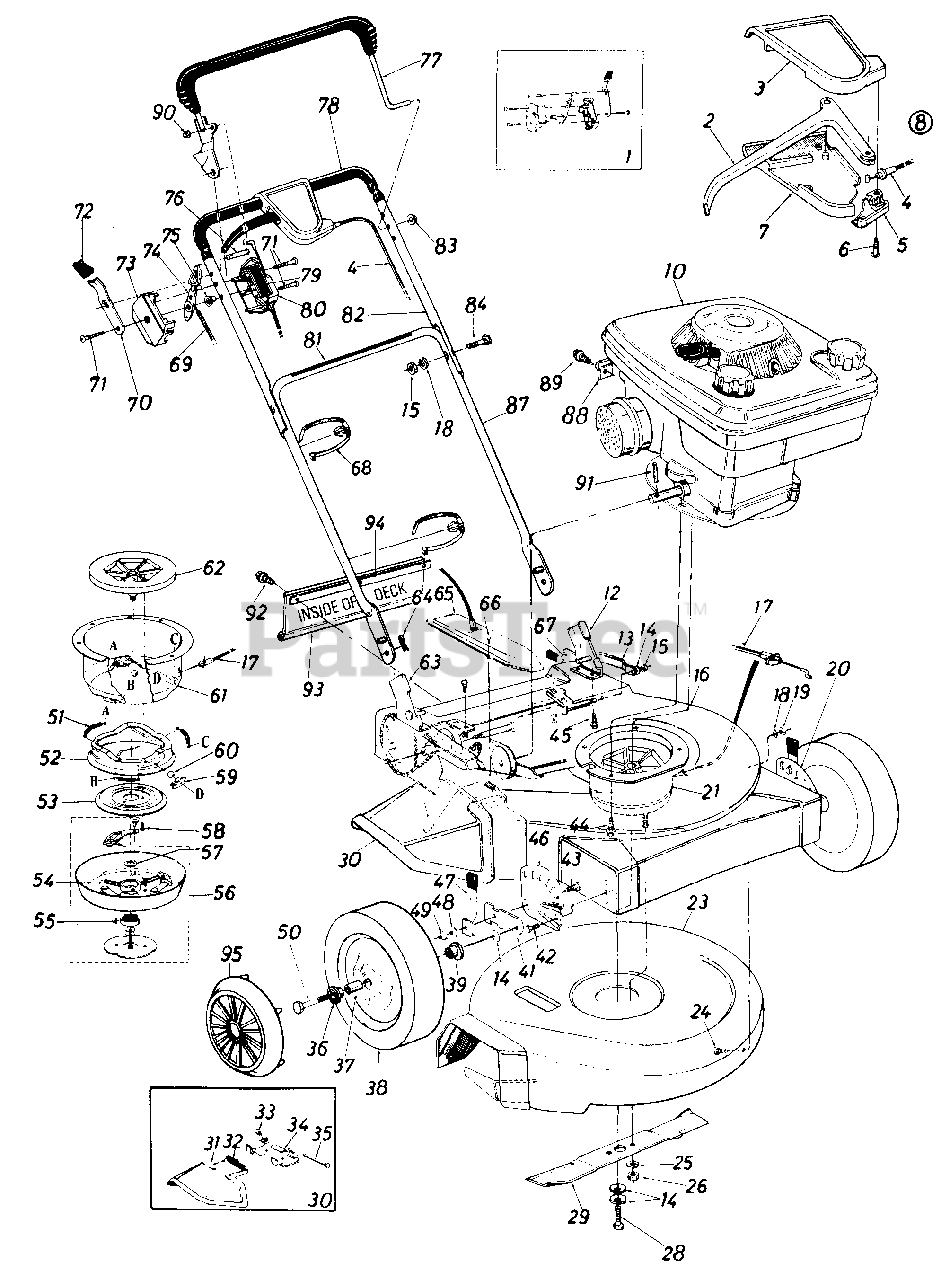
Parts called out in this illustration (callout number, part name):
1	Control Housing Comp.
2	Control Lever
3	Control Cover Half-Upper
4	Drive Clutch Cable-59"
5	Cable Mounting Cap
6	Flat "C" Sunk Hd. Tap Scr. #10 x .75" Lg.
7	Control Cover Half-Lower
8	Clutch Control Housing Comp.
10	Engine
12	Handle Mount Brkt. Ass'y.-L . H .
13	Pivot Brkt. Ass'y.-L.H.
14	Belleville Wash. 3/8" I.D.
15	Hex Nut 5/16-18 Thd.
18	L-Wash. 5/16" I.D.
19	Hex Nut 5/16-18 Thd.*
20	Height Adj. Ass'y. Comp.-L.H .
21	Blade Brake/Clutch Ass'y.-Comp.
23	Lower Deck Ass'y.
24	Carriage Bolt 5/16-18 x .62"
25	L-Wash. 3/8" I.D.
26	Hex Nut 3/8-24 Thd. (Grade 8)
28	Hex Bolt 3/8-24 x 2.00" Lg. (Grade 8)
29	21" Blade
30	Chute Deflector Ass'y.-Comp .
31	Chute Deflector
32	Torsion Spring
33	Push Nut 1/4" Rod
34	Adapter Plate
35	Pivot Pin
36	Ball Bearing 3/8" I.D.
37	Spacer
38	Wheel Ass'y. Comp. 8 x 1.75
39	Ball Bearing 1/2" I.D.
41	Pivot Bar
42	Hex Sems Bolt 3/8-16 x .62"
43	Shoulder Bolt
44	Hex Wash. Hd. TT-Tap Scr. 3/8-16 x 1" Lg.
45	Hex Wash. Hd. "B"-Tap Scr. 5/16 x 1/2 " Lg.
46	Height Adjuster Ass'y. Comp.-R.H.
47	Spring Lever Ass'y. w/Knob
48	Bell-Wash. .400" I.D. x 1.13"
49	Hex Ins. L-Nut 3/8-24 Thd.
50	Axle Bolt
51	Extension Spring
52	Brake Cup Cone
53	Clutching Cone
54	Compression Spring
55	Ball Bearing
56	Clutch Blade Housing Ass'y.
57	Fl-Wash. .69" I.D. x 1.06"
58	Hex TT-Tap L-Scr. '/4-20 x .75" Lg.
59	Ball Block
60	Steel Ball 1/2" Dia.
61	Clutch Housing
62	Fan Adapter
63	Handle Mount Brkt. Ass'y.-R. H.
64	Internal Cotter Pin 5/16" Dia.
65	Belt Cover
66	Hex Wash. Hd. "AB" Tap Scr. #10 x .50" Lg.
67	Index Plate Ass'y.-L.H.
68	Cable Tie
69	Throttle Wire-43"
70	Lockout Spring
71	Truss Mach. Tap Scr. #12 x 1.5" Lg.
72	Spring Lever Knob
73	Control Panel Half
74	Throttle Control Lever
75	Control Disc Pin
76	Lock Pin
77	Control Handle-R.H.
79	Control Label-Throttle
80	Clutch Panel Half
81	Instruction Label-Handle
82	Upper Handle
83	Cap Speed Nut 5/16" Rod
84	Curved Carriage Bolt 5/16-18 x 1.38" Lg.
87	Lower Handle
88	Casing Clamp
89	Hex Sems Scr. #10-32 x .62"
90	Push Cap
91	Spring Pin 3/16" Dia. x 1.5"
92	Hex Wash. Hd. AB-Tap Scr. 1/4 x.62" Lg.
93	Rear Flap
94	Retaining Strip
95	Hub Cap
